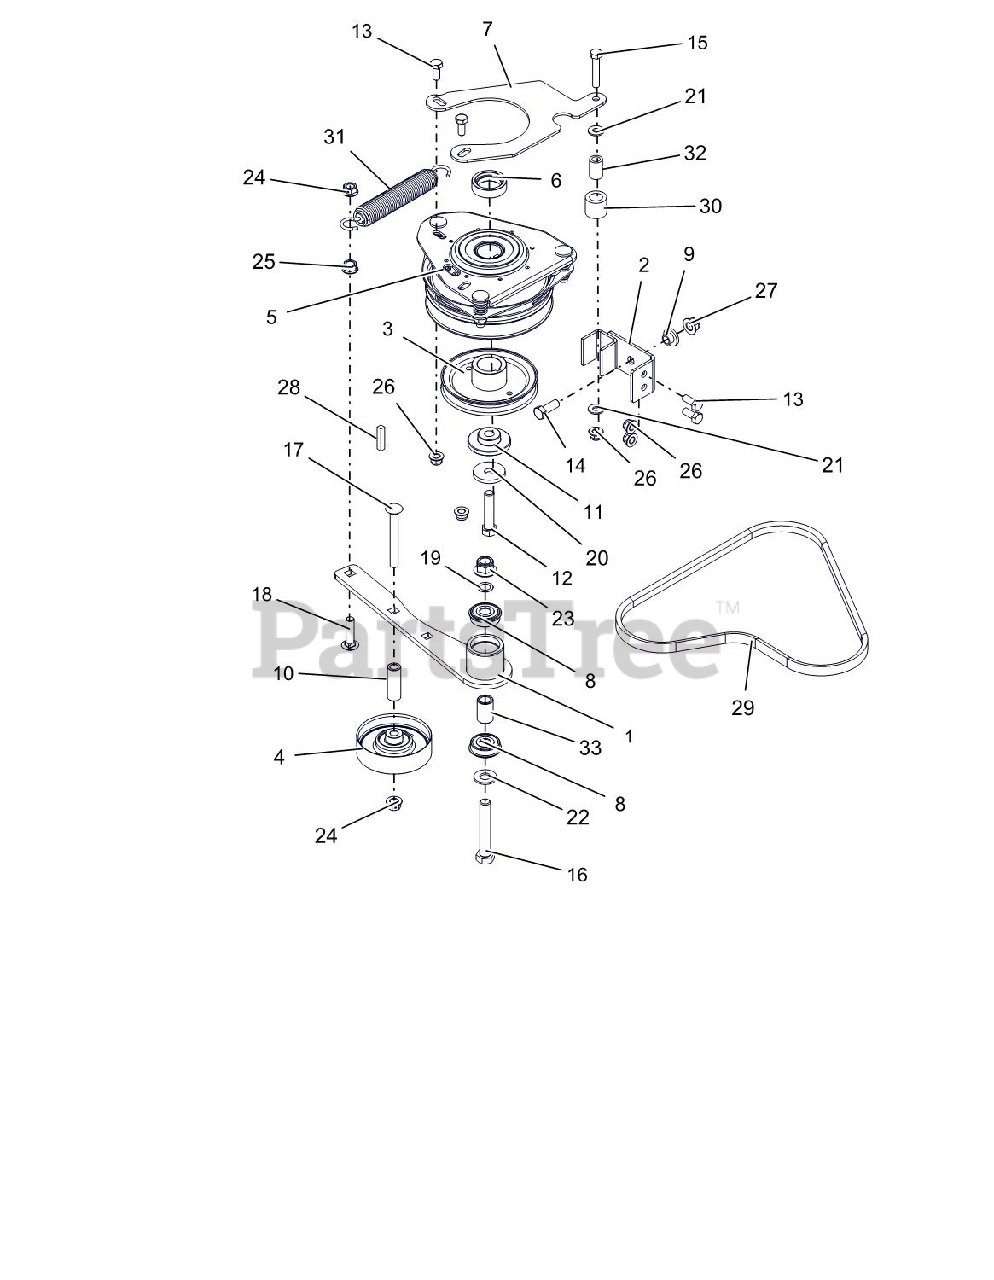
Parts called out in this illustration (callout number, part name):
1	WLDMT, HYDRO DRIVE IDLER ARME
2	WLDMT, CLUTCH STOP
3	SHEAVE, ENGINE 4.50 X 1.127
4	IDLER, FLAT 3.5" NO FLANGES
5	CLUTCH, OGURA GT1A-AR03
6	SPCR, CLUTCH
7	PLATE, CLUTCH DOG
8	BRG-BALL .50X1.38X.438 SEALED
9	BSHG-FLG .385X.500X.875X.406
10	BSHG, SLV .375 X .75 X 1.75
11	BSHG-FLG .469X1.06X.574X2.0
12	BLT-HEX .438-20X2 G8YZ NYTORQ
13	@BLT-HEX .31-18X.75 GR5 YWZC
14	@BLT-HEX .38-16X1.00 GR5 YWZC
15	@BLT-HEX .31-18X1.75 GR5 YWZC
16	@BLT-HEX .50-13X3.00 GR5 YWZC
17	BLT-RDHDSQNK .38-16X3.25 GR5YZ
18	@BLT-RDHDSQNK .38-16X1.50 G5YZ
19	WASHER, .500X.750X.020 THRUST
20	WASHER, 7/16" SPRING DISK
21	@WSHR-FL-STL.312X.734X.065 YWZ
22	@WSHR-FL-STL.531X1.06X.095YWZC
23	@NUT-LK-NYL-FLG .50-13 YWZC
24	NUT-LK-CTR-FLG .38-16 YWZC
25	@NUT-SPNLK-FLG .375-16 YWZC
26	@NUT-LK-NYL-FLG .31-18 YWZC
27	@NUT-LK-NYL-FLG .38-16 YWZC
28	KEY-SQ .25 X 1.25 X .25 SAE
29	BELT, 4L RAW EDGE 37.900"
30	BUMPER,RUBBER .62X1.0X.88 LG
31	SPRING, EXTENSION 1.0 X 6.65
32	BUSH.,S.391X.622X.950 ST
33	SPACER .510 X .75 X 1.1485
